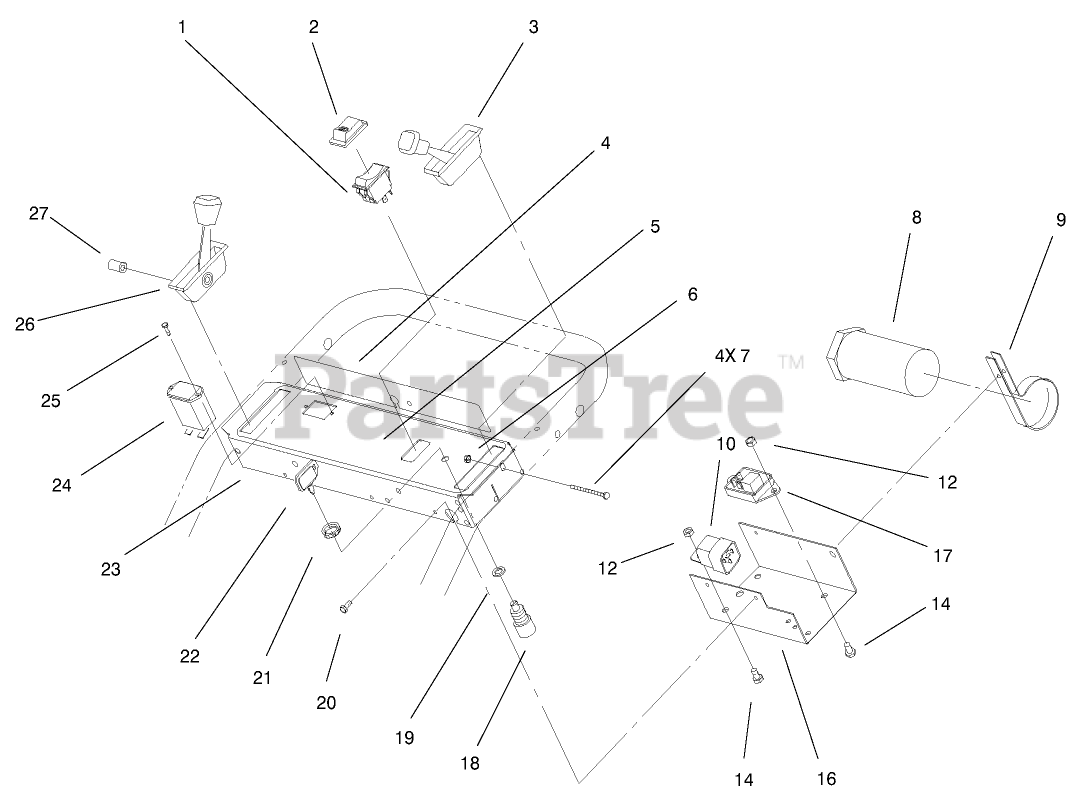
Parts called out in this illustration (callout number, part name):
1	SWITCH
2	BOOT-SWITCH
3	CONTROL - THROTTLE
4	DECAL-WARNING
5	DECAL - CONTROL PANEL
6	NUT-LOCK, NI
7	SCREW-SHH
8	TUBE-MANUAL
9	CLAMP-R
10	RELAY
12	NUT-LOCK, NI
14	SCREW-HH
16	PANEL-BOTTOM
17	MODULE-DELAY
18	SWITCH-STARTER
19	WASHER-TOOTH, INTERNAL
20	SCREW-HWHTF
21	NUT-HH
22	KEY-IGNITION
23	PANEL - CONTROL
24	HOURMETER
25	SCREW-HWH
26	CONTROL - CHOKE
27	SPACER
